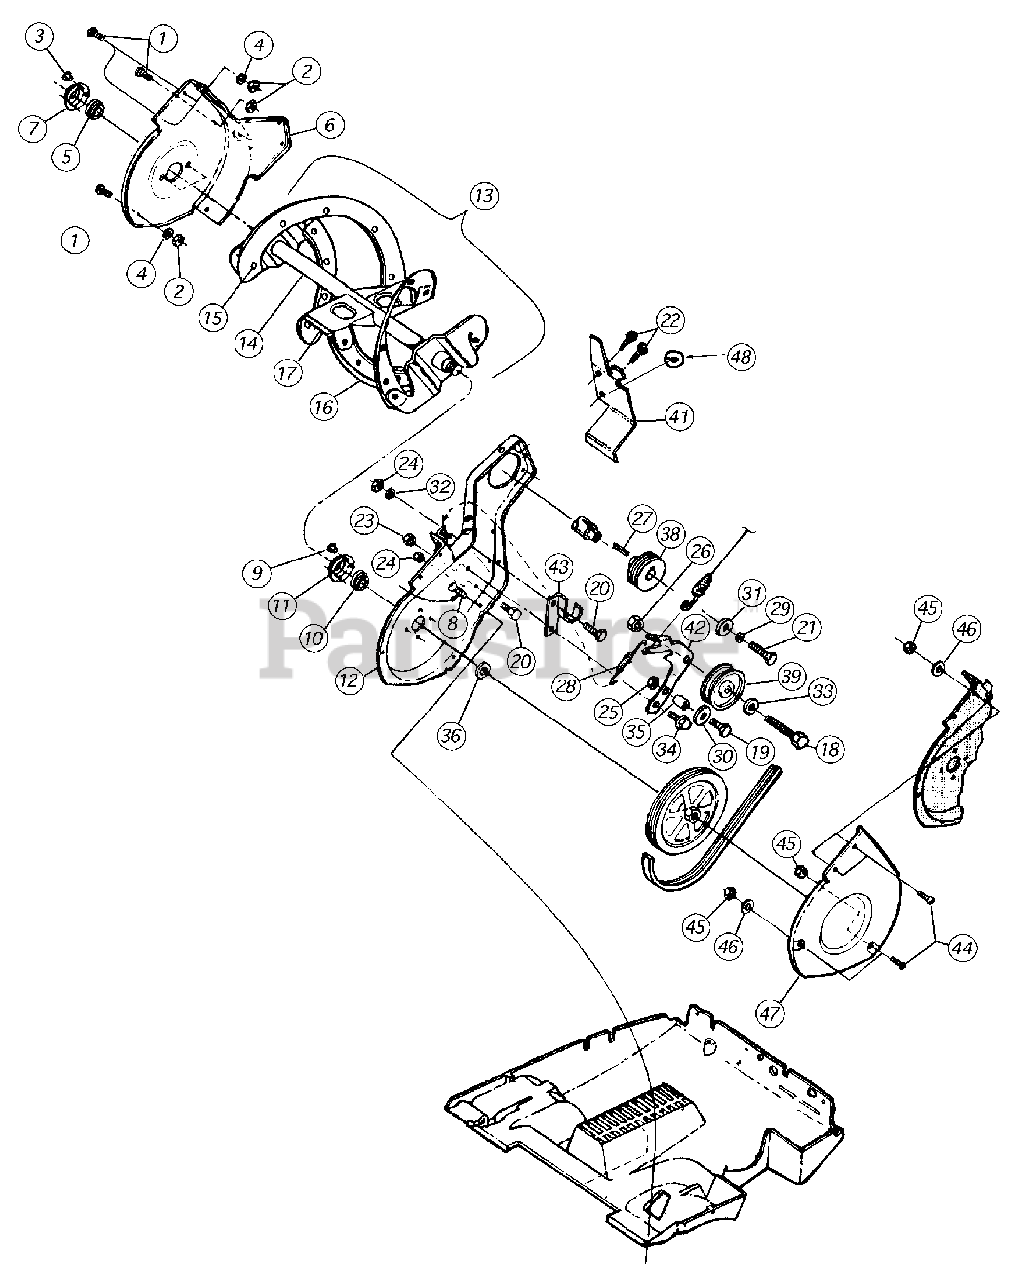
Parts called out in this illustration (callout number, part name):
1	Scr: #10-24:.625 Pan Trx
2	Hex Nut
3	Rivet
4	Flat Washer
5	Ball Bearing, Auger Axle
8	Hex Screw: 1/4 - 20 X .625 Gr 2
9	Rivet .252 Dia X .31
10	Ball Bearing, Auger Axle
11	Retainer Bearing
14	Auger Assembly, Weld.
15	Rivet, Truss
16	Auger Blade
17	Auger Paddle
18	Hex Screw: 3/8 - 16 X 1.50 Gr 5
19	Hex Screw: 1/4 - 20 X 1.0 Gr 5
20	Scr:AB: 1/4-14: .625:Hxindwsh
21	Hex Screw: 5/16 - 24 X .88 Gr 2
22	Hex Screw
23	Nylock
24	Top Lock Nylon Insert
25	Lock Nut: 1/4 - 20
26	Flanged Lock Nut
27	Key
28	Extension Spring
29	Lock Washer
30	Flat Washer: .344 ID X 1.12 OD
31	Flat Washer: .385 ID X .87 OD X .092
32	Flat Washer: .25 ID X .62 OD
33	Flat Washer: .406 ID X .81 OD X .051
34	Shoulder Screw
35	Spacer, Brake Belt
36	Spacer, Auger Pulley
38	Engine Pulley
39	Idler Pulley
43	Bracket, Belt
44	Machine Screw #10 - 24 X .62
45	Hex Nut
46	Flat Washer: .218 ID X .62 OD X .063
